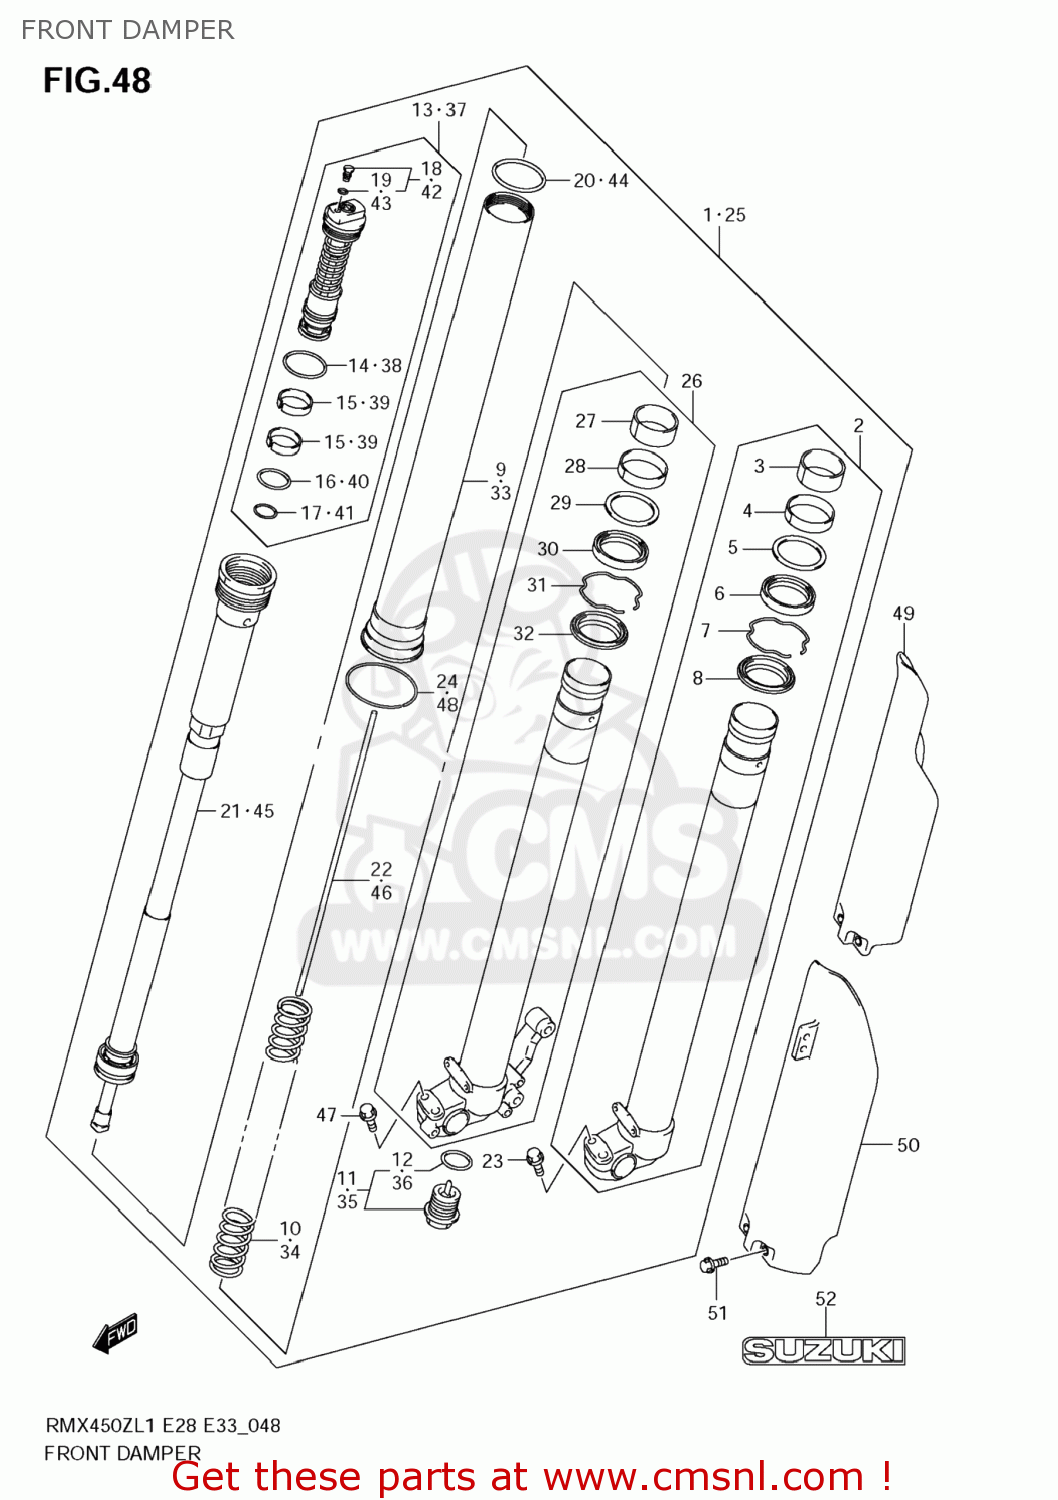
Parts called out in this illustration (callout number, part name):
1	DAMPER ASSY,FR FORK,R
2	TUBE,INNER,R
3	BUSH
4	BUSH,GUIDE
5	SPACER,SEAL
6	SEAL,OIL
7	RING,OIL SEAL STOPPER
8	SEAL,DUST
9	TUBE,OUTER
10	SPRING,FR(K=0.47)
11	BOLT,CTR
12	O RING
13	BOLT,FORK
14	O RING
15	BUSH
16	O RING
17	O RING
18	BOLT,PLUG
19	O RING,PLUG
20	O RING
21	ROD,DAMPER
22	ROD,PUSH
23	BOLT
24	STOPPER,RING
25	DAMPER ASSY,FR FORK,L
26	TUBE,INNER,L
27	BUSH
28	BUSH,GUIDE
29	SPACER,SEAL
30	SEAL,OIL
31	RING,OIL SEAL STOPPER
32	SEAL,DUST
33	TUBE,OUTER
34	SPRING,FR(K=0.47)
35	BOLT,CTR
36	O RING
37	BOLT,FORK
38	O RING
39	BUSH
40	O RING
41	O RING
42	BOLT,PLUG
43	O RING,PLUG
44	O RING
45	ROD,DAMPER
46	ROD,PUSH
47	BOLT
48	STOPPER,RING
49	PROTECTOR,FR FORK,R
50	PROTECTOR,FR FORK,L
51	BOLT(6X10)
52	EMBLEM,SUZUKI
